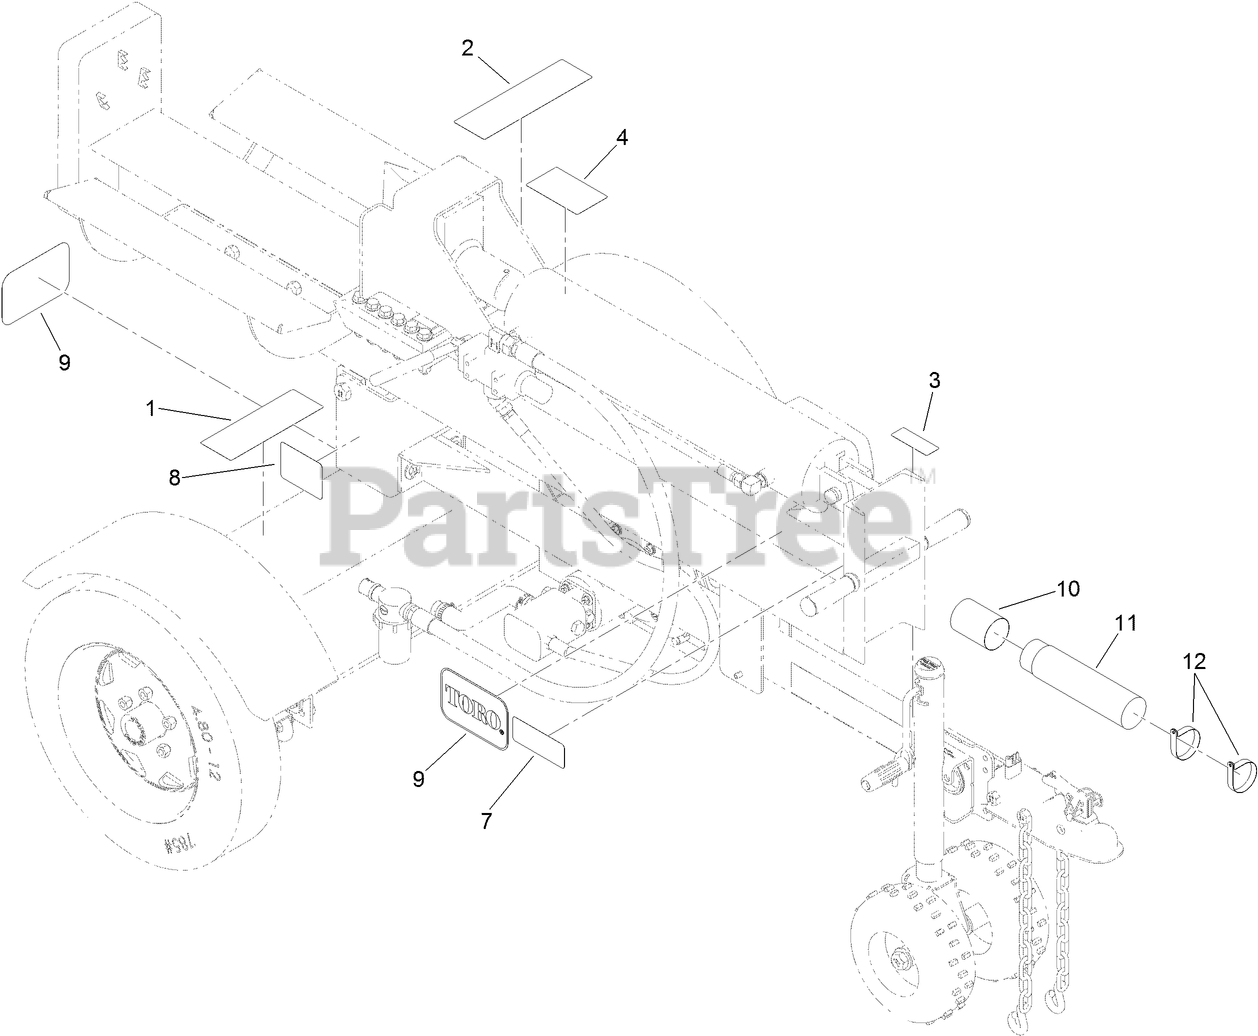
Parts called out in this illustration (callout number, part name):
1	DECAL-CAUTION
2	DECAL-WARNING
3	DECAL-CAUTION
4	DECAL-CAUTION
8	DECAL-TON
9	DECAL
10	CAP-HOUSING
11	TUBE-MANUAL
12	CLAMP-R
